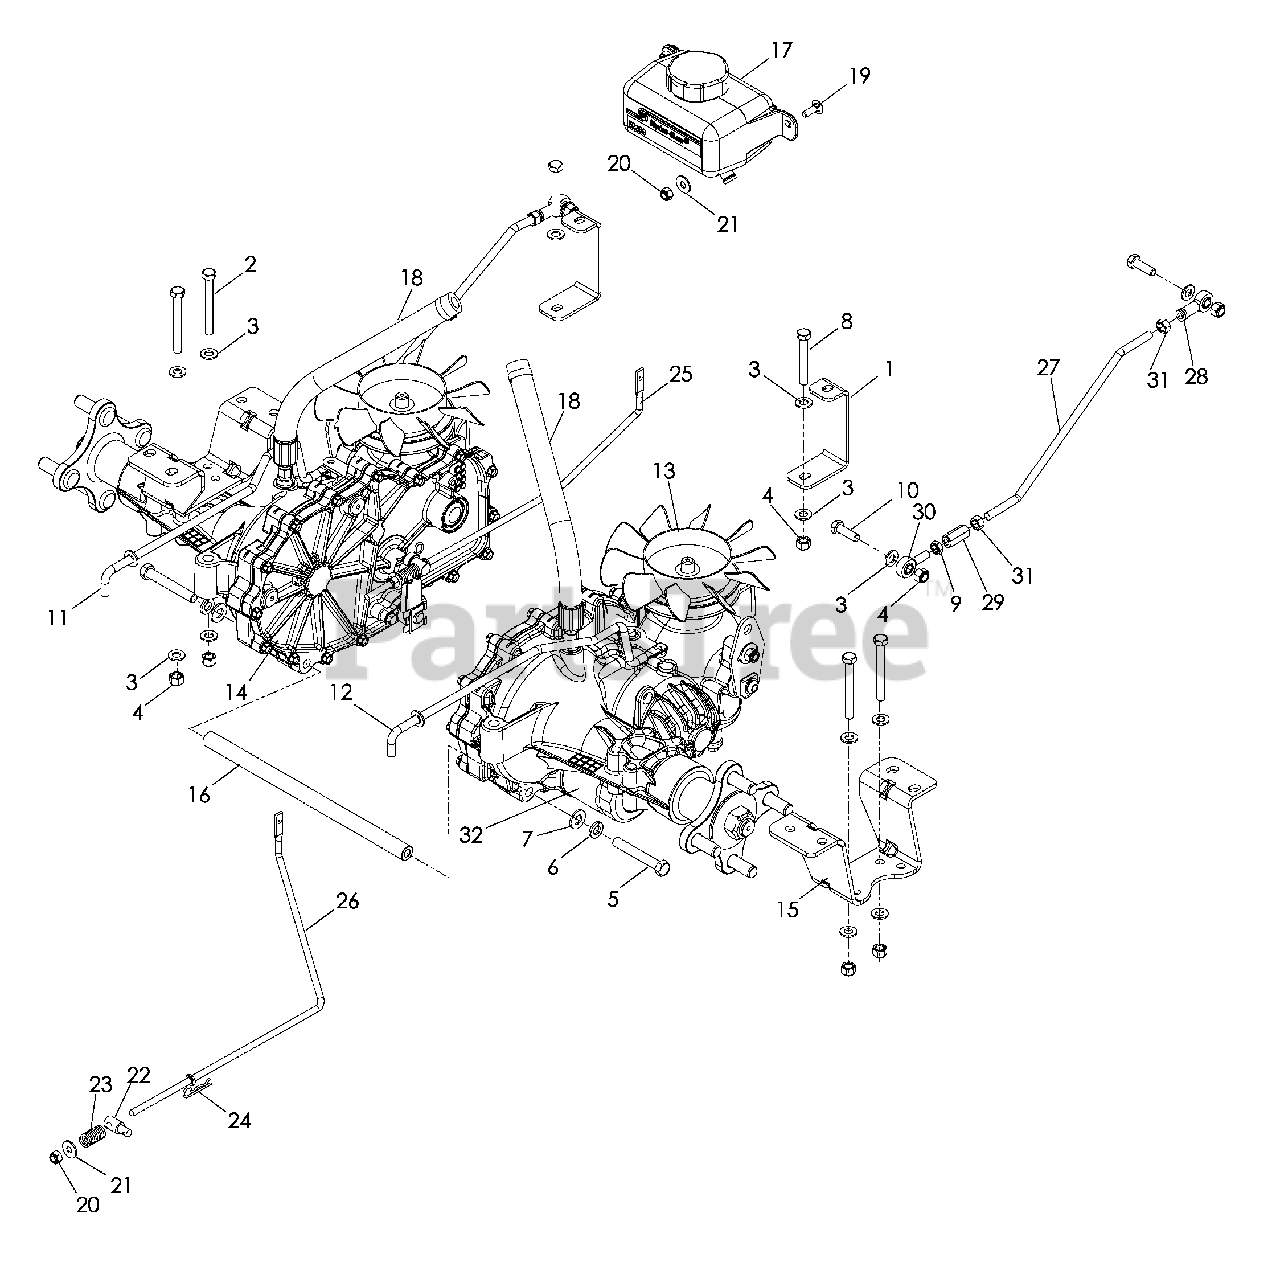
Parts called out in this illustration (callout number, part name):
1	SUPPORT, TRANSMISSION
2	HCS 5/16-18 x 2¾
3	WASHER 5/16 SAE FLAT
4	NUT 5/16-18 HEX NYLOC
5	HCS 3/8-16 x 2½
6	WASHER, 3/8 SPLT LOCK
7	WASHER 3/8 SAE FLAT
8	HCS 5/16-18 x 2¼
9	NUT 5/16-24 HEX JAM LH
10	HCS 5/16-18 x 1
11	LINK ARM, BYPASS, RT
12	LINK ARM, BYPASS, LT
13	TRANS, ZT-2800 RT
14	TRANS, ZT-2800 LT
15	EZT MOUNT, REAR
16	SPACER TUBE, EZT
17	EXPANSION TANK w/CAP
19	RHSNB ¼-20 x ¾ GR2
20	NUT ¼-20 HEX NYLOC
21	WASHER ¼ FLAT
22	BRAKE SWIVEL
24	HAIRPIN COTTER
25	ROD, EZT BRAKE LT
26	ROD, EZT BRAKE RT
27	ROD, MOTION CONTROL
28	ROD END RH
29	COUPLER, ROD END
30	ROD END MALE LH
31	NUT 5/16-24 HEX
